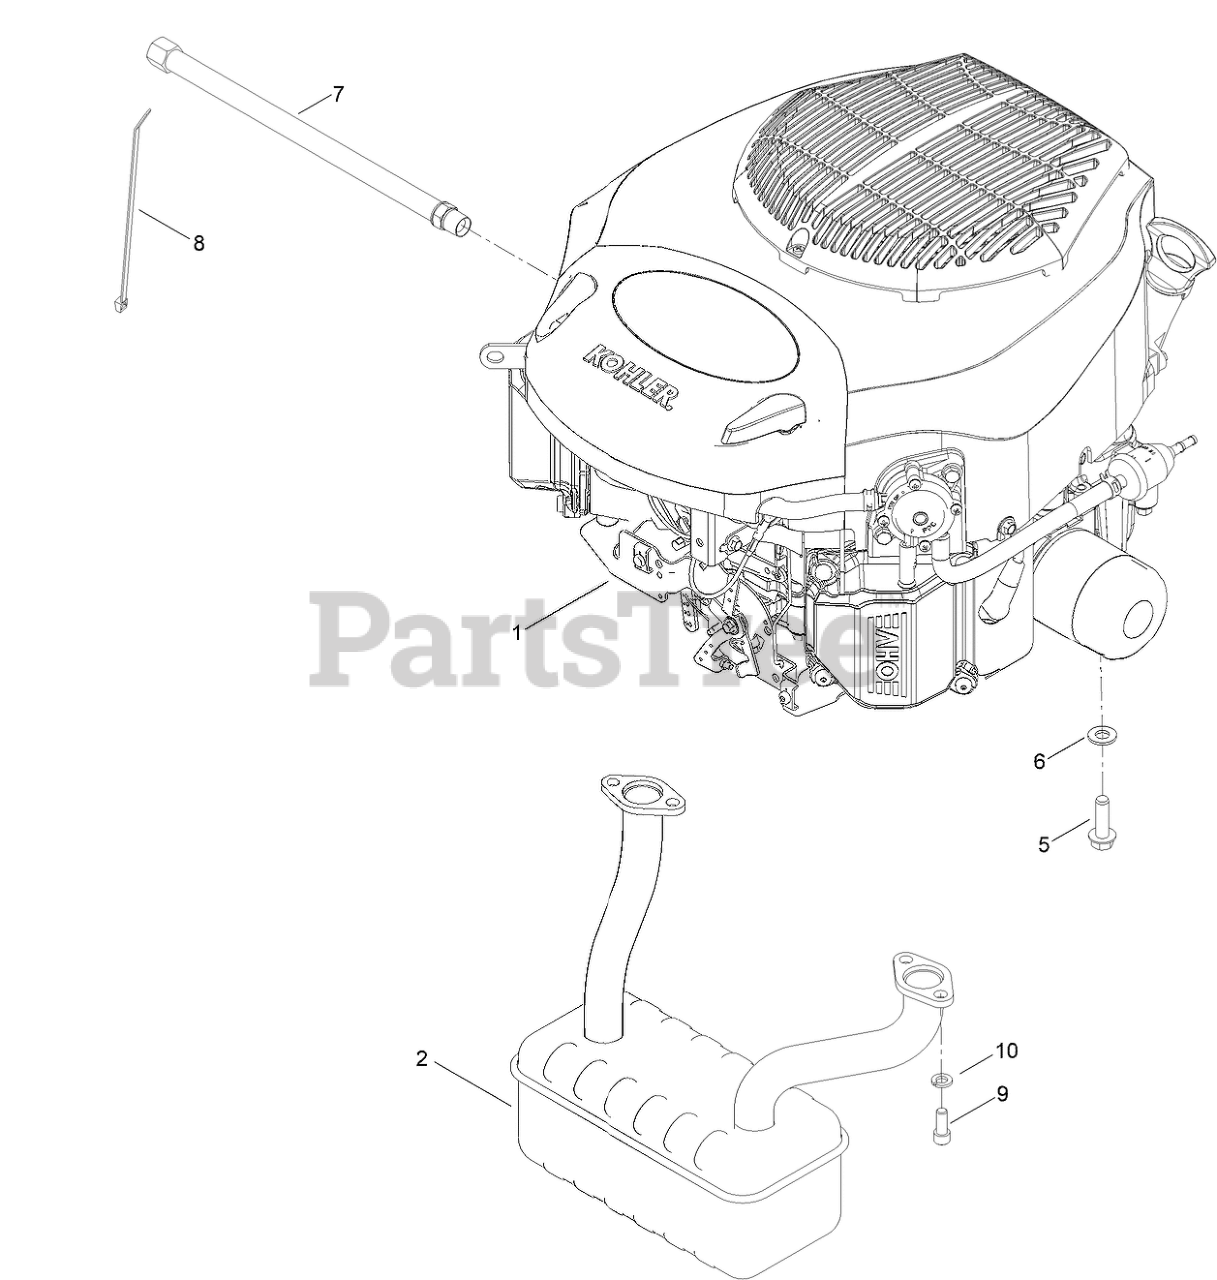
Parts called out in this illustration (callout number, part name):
2	MUFFLER
5	SCREW-THD
6	WASHER-FLAT
7	HOSE-DRAIN, OIL
8	TIE-CABLE
9	SCREW-HSH
10	WASHER-LOCK
